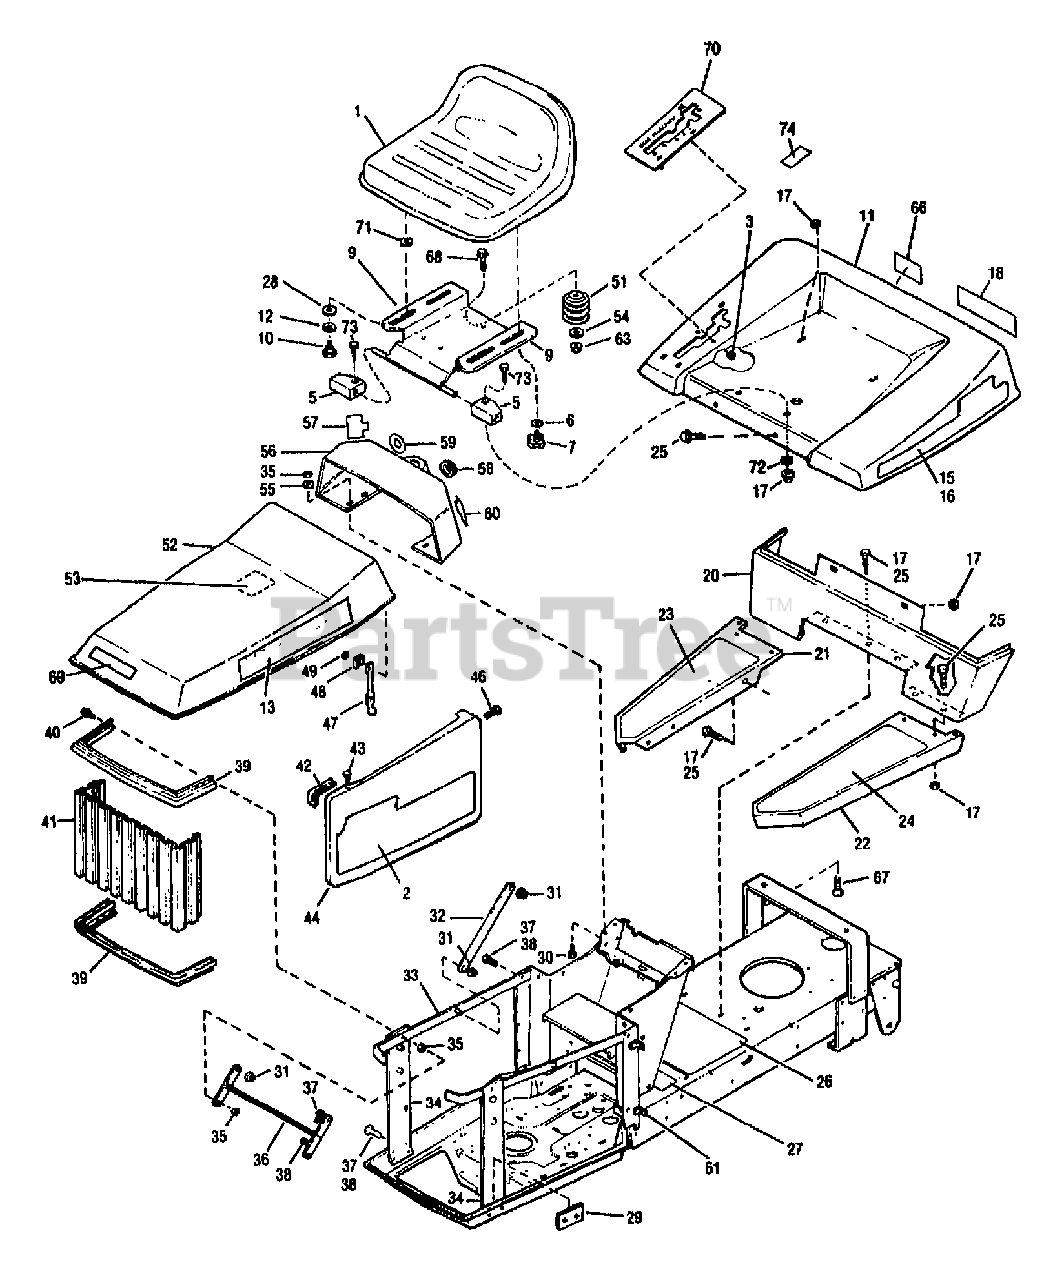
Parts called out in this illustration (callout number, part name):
2	DECAL-SIDECVR LH RED
2	DECAL-SIDECVR RH RED
3	NUT-SELF THREADING
5	BLOCK-PIVOT
6	WASHER-FLAT 3/8 SAE
9	ASSM-SEAT SUPPORT
10	SCR-SHLDR 3/8-16X.25 G5ZP
11	FENDER-REAR
12	WASHER-1.06X.51X.09 NYLON
13	DECAL-LOGO
15	DECAL-FENDER RH RED
16	DECAL-FENDER LH RED
17	NUT-HFLK 5/16-18 ZP
18	DECAL-LOGO FENDER
20	SUPT-RUNNING BOARD
21	BOARD-RUNNING RH
22	BOARD-RUNNING LH
23	PAD-FOOT RH
24	PAD-FOOT LH
25	SCR-LOCK
26	PAD-FOOT CENTER
27	DECAL-INSTRUCTION
28	WASHER-BOW .74X.52X.01
29	SPACER-PLATE
31	RETAINER-PUSH ON .24X.73 ZP
33	ASSM-HINGE STRAP
34	ASSM-GRILLE SUPT (RED)
35	NUT-HT LK 1/4-20
36	LINK-HINGE
37	SCR-HH 1/4-20X.625
38	NUT-HF/LK 1/4-20 ZP
41	GRILLE-BLACK
42	GUIDE-SIDE CVR (RED)
43	RIVET-POP
44	COVER-SIDE LH RED
44	COVER-SIDE RH RED TRACTOR
47	LATCH-RUBBER
49	NUT W/LKWASHER 10-24 ZP
51	SPRING-COMPRESSION
52	ASSM-HOOD RED
53	DECAL-SVC INST
54	WASHER-FLAT 1.25X.406X.179
56	PANEL-INSTRUCTION
57	DECAL-THROTTLE
59	DECAL-IGNITION
60	DECAL-CHOKE
61	NUT-SPEED
63	NUT-HFLK 3/8-16 ZP
67	BOLT-CARR 5/16-18X.63 ZP
68	SCR-HFLK 3/8-16X1.00 ZP
69	DECAL-LOGO
70	QUADRANT-SHIFT
71	WASHER-FLAT
72	WASHER-1.5X.343X.104
73	SCR-HH 5/16-18X1.5 G5 ZP
74	DECAL-U.S.A.
